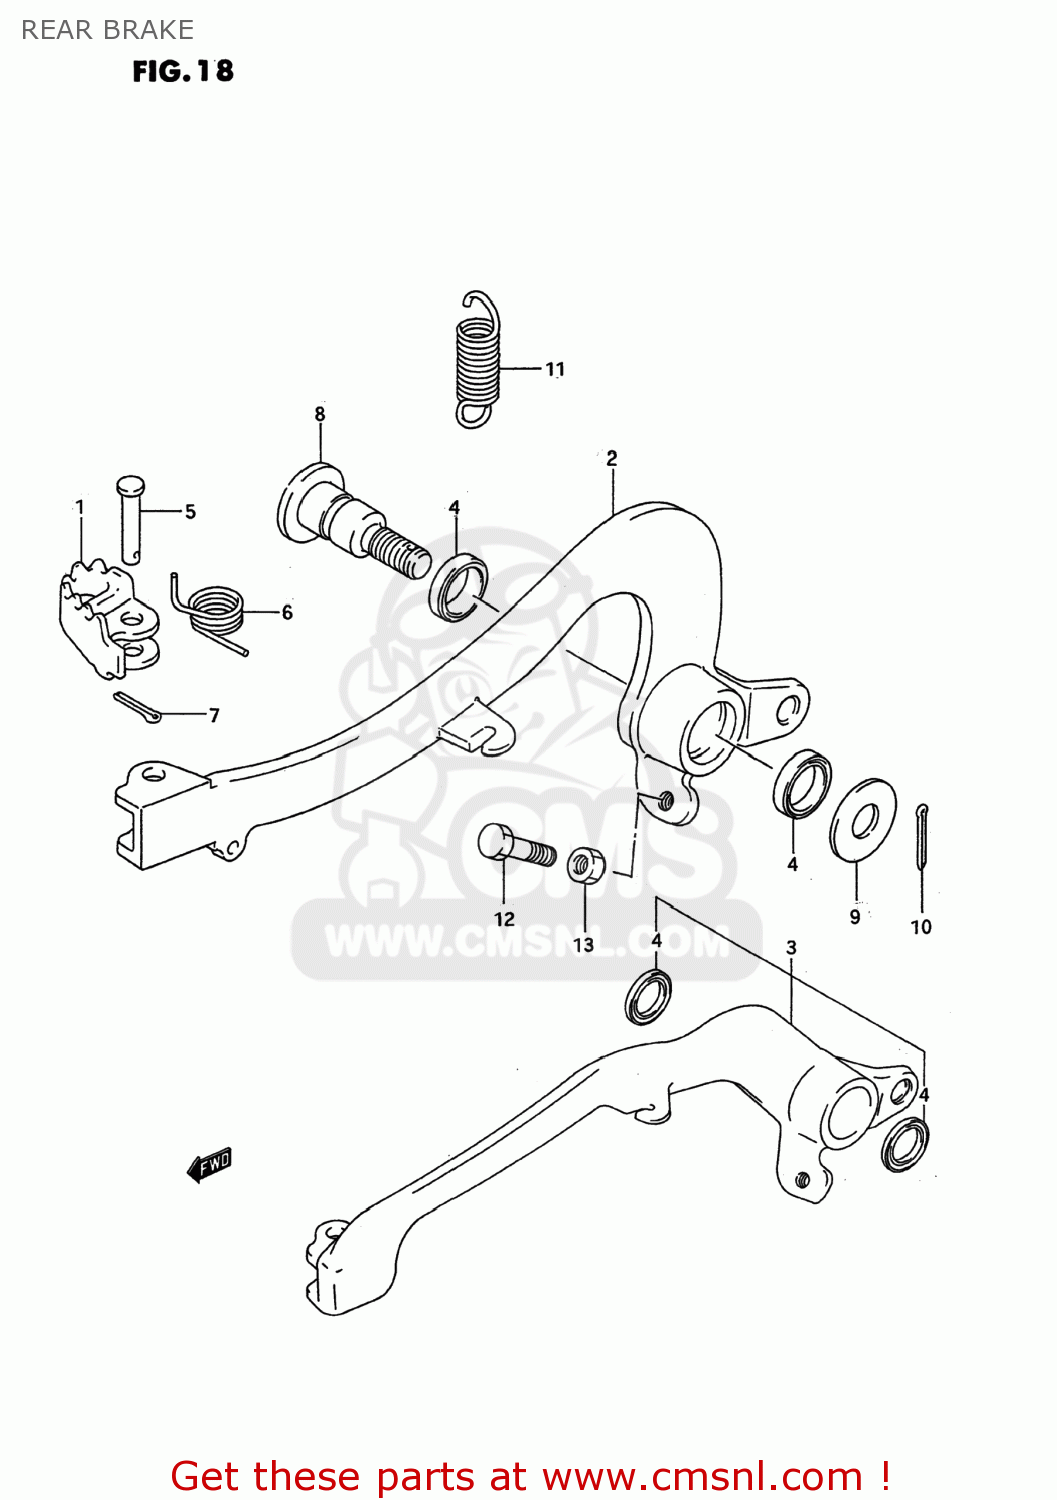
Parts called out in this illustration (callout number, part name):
1	PEDAL,BRAKE
2	ARM COMP,BRAKE PEDAL
3	ARM,BRAKE PEDAL
4	SEAL,OIL(15X21X3)
5	PIN(6X23.5)
6	SPRING
7	PIN
8	SHAFT,BRAKE PEDAL
9	WASHER
10	PIN 20X20
11	SPRING
12	BOLT(6X23)
13	NUT
